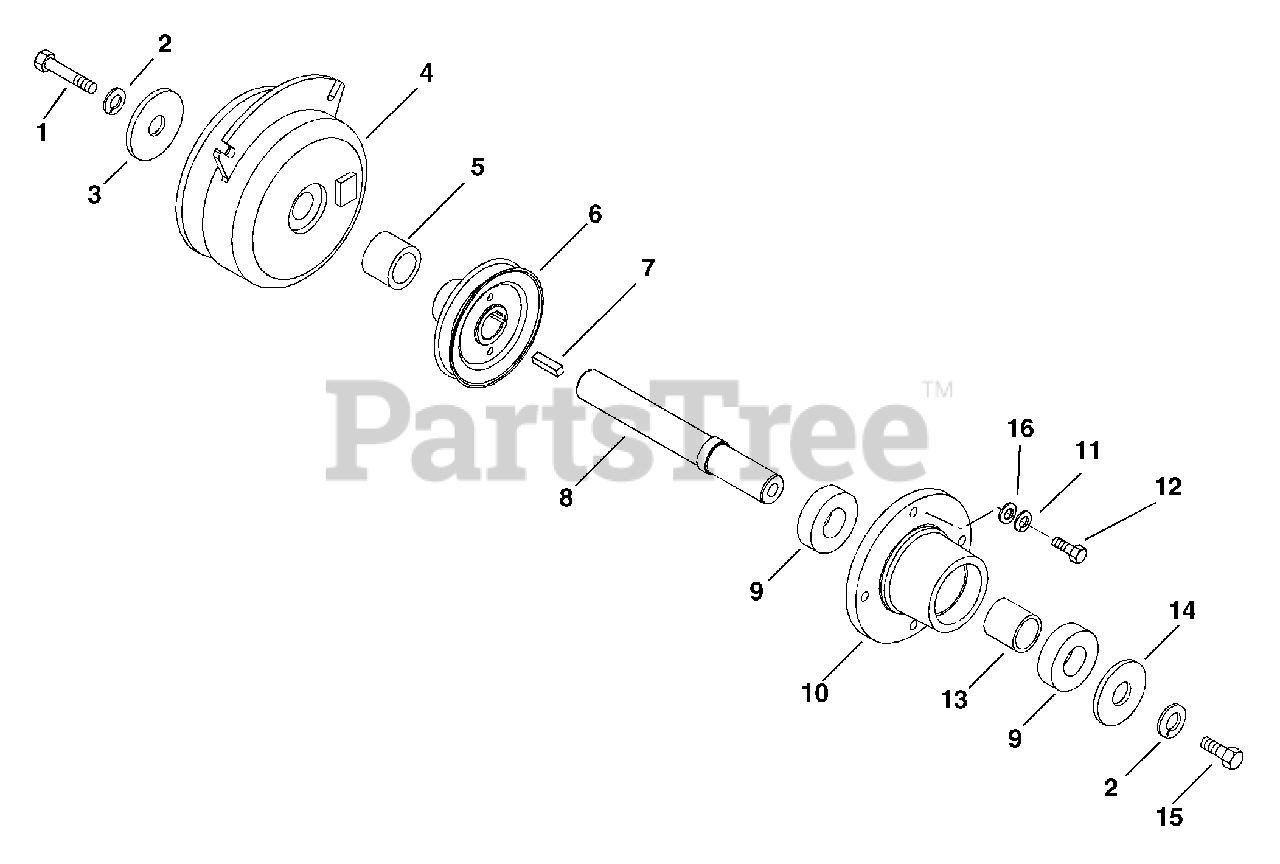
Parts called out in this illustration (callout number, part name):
1	Bolt-Hex .44-20 x 2.50 Grade 5
1	Bolt-Hex .44-20 x 1.50 Grade 5
2	Washer-Locking .44 x .109
3	Washer-Flat-Steel .469 x 2.00 x .25
4	Clutch-Electric/Brake
5	Spacer 1.004 x 1.500 x .740
6	Sheave- Jackshaft 4.50
7	Key-Square .25 x 1.00 x .25 SAE
8	Shaft-Jack
9	Bearing-Ball .984 x 2.04 x .59
10	Housing-Transmission Spindle
11	Washer-Locking .31 x .078
12	Bolt-Hex .31-18 x .75 Grade 5
13	Spacer 1.00 x .253 x 1.26
14	Washer-Flat-Steel .463 x 1.38 x .25
15	Bolt-Hex .44-20 x 1.00 Grade 5
16	Washer-Flat-Steel .328 x 1.00 x .094
